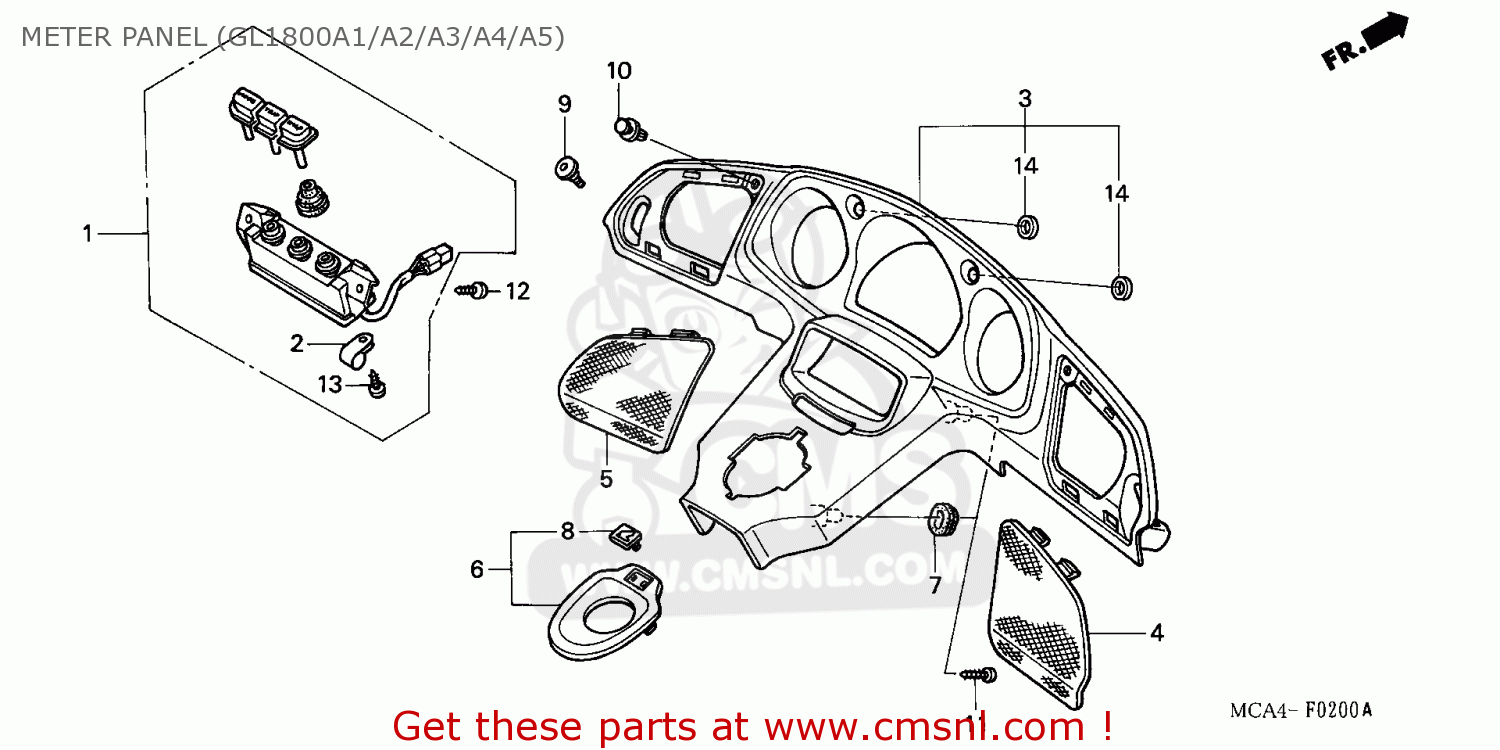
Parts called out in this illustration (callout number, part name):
1	SW ASSY,METER
2	CLAMP
3	PANEL,MET*NH389M*
4	COVER,R SPEAKER
5	COVER,L SPEAKER
6	COVER,COMB SW
7	GROMMET,A/C.CASE
8	EMBLEM,WING MARK
9	SCREW,PAN 6X14
10	CLIP, SPLASH SHIELD
11	SCREW,TAPG,4X25
12	SCREW,4X12
13	SCREW 4X16
14	SEAL,WINKER
